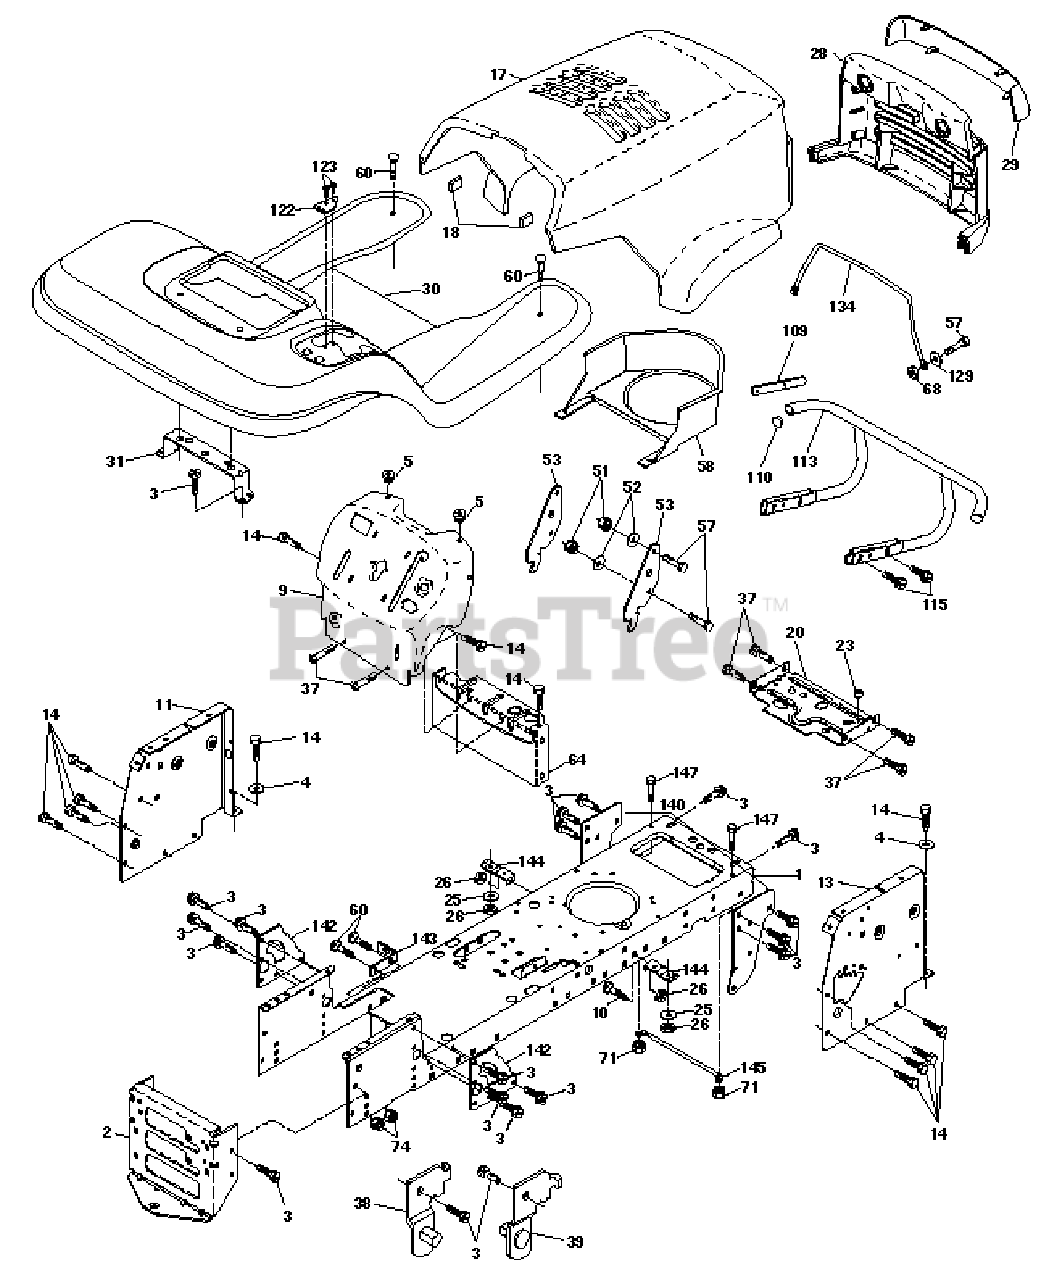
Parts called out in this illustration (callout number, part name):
1	Chassis Weldment
2	Drawbar, Stretch
3	Screw Thdrol 3/8-16x3/4 Ty-tt
4	Washer 13/32 x 3/4 x 16 Ga.
5	Bumper Hood/Dash
9	Dash Slkscr
10	Bolt Carriage 3/8-16 x 1
11	Panel Dash Lh
13	Panel Dash Rh
14	Screw Thdrol 3/8-16x1/2 Ty-tt
17	Hood LT/PL Husqvarna
18	Bumper, Hood
20	Plate Mtg Battery Fuel Tank Fr
25	Washer 13/32 X 13/16 X 12 Ga
26	Nut Lock Hex W/Ins 3/8-16 Unc
28	Grille LT/PL Husqvarna
29	Lens LT/PL Husqvarna
30	Fender Footrest STLT Pnt
31	Bracket Support Fender
37	Screw Thdrol 6/16-18 x 1/2 TYT
38	Bracket, Asm. Pivot, L.H., Mower Rear
39	Bracket, Asm. Pivot, R.H., Mower Rear
51	Nut Lock Hex W/Ins 1/4-20
52	Washer 9/32 x 7/8 x 16 Ga.
53	Bracket Pnt. Pick off LT/PL Husqvarna
57	Bolt Hex 1/4-20 x 3/4
58	Air Duct Engine CV18
60	Bolt Rdhd Sqnk 3/8-16unc x 3/4
64	Dash Lower STLT
68	Nut Keps Hex 1/4-20 Unc
71	Nut Crownlock 1/4-20 Unc
74	Nut Crownlock 3/8-16 UNC
109	Bracket Extension Bumper
110	Plug Plastic
111	Bolt Rdhd 3/8-16unc x 1-1/2
112	Washer 13/32 x 13/16 x 16 Ga.
113	Bumper Asm.
122	Bracket Shift STLT
129	Washer 9/32 x 5/8 x 16 Ga.
134	Rod Support Hood LT/PL Husq.
140	Bracket Chassis Front 7 Ga.
142	Plate Reinforcement STLT
143	Bracket Swaybar Chassis
144	Bracket Pnt Footrest STLT
145	Rod Pivot Chassis/Hood
146	Screw Torx Hd Thd 5/16-18 UN-2A
147	Bolt Hex Hd 1/4-20unc x 3/4
